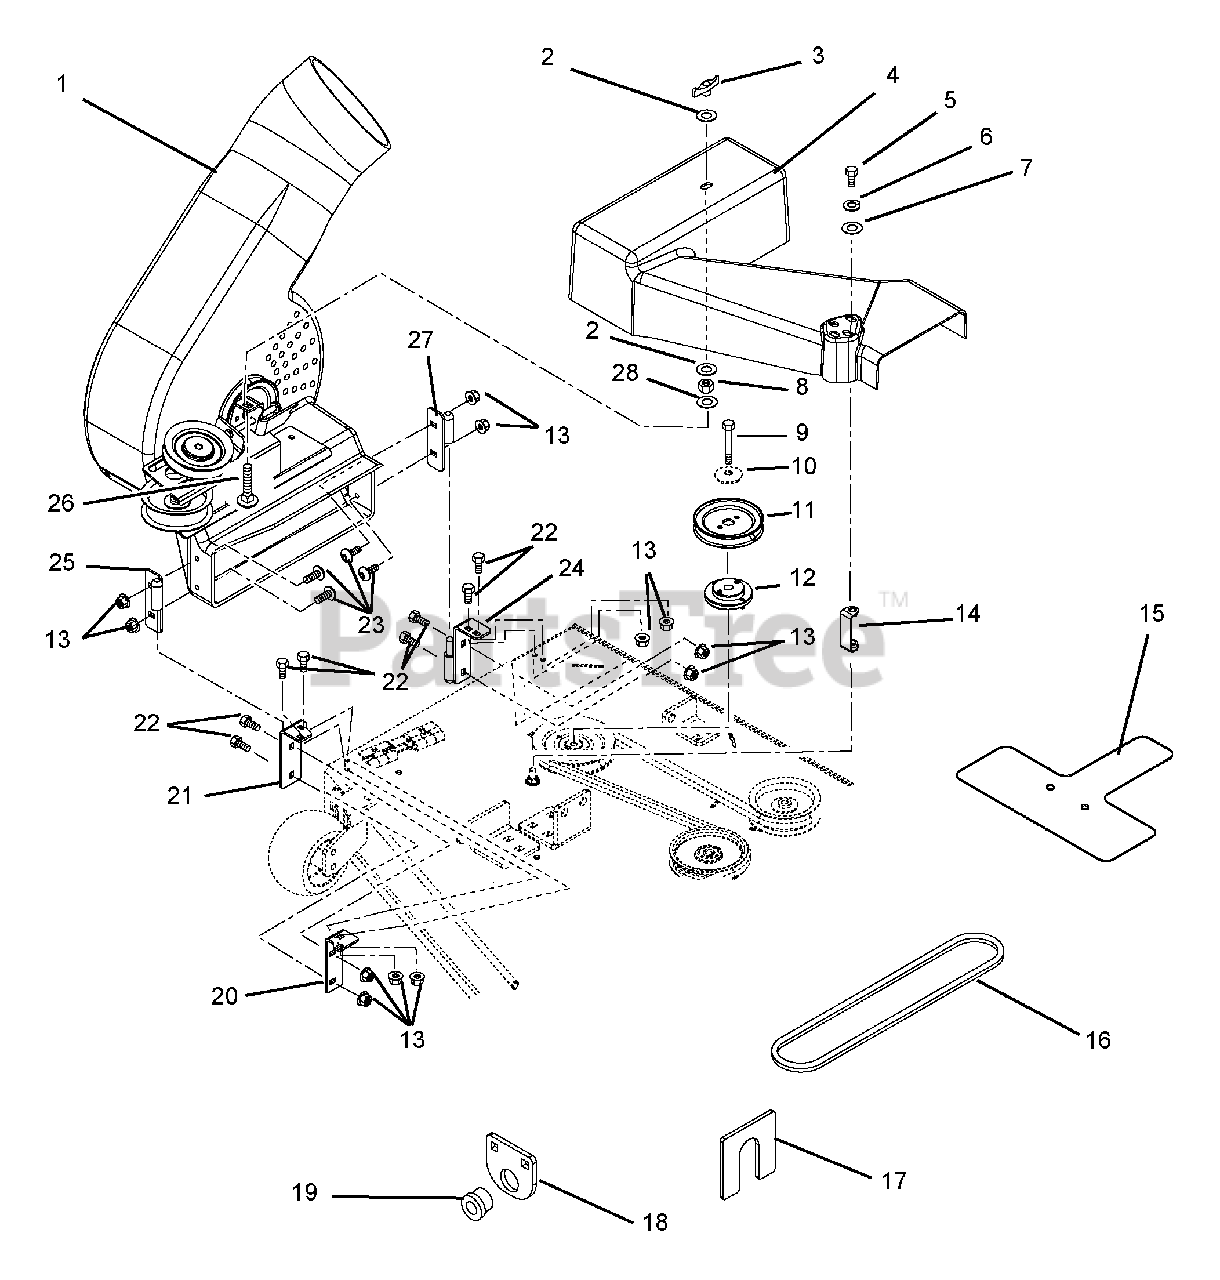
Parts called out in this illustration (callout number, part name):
1	Housing, Blower
2	Washer-Flat-Steel.38 x 1.50 x .062
3	Knob- Wing .312-18
4	Belt Cover
5	Bolt-Hex .38-16 x .75 - Grade 5
6	Washer-Locking .38 x .094 Regular
7	Washer-Flat-Steel .438 x 1.00 x .083
8	Nut-Jam .312-18
9	Bolt-Hex .38-16 x 1.75 - Grade 8
10	Washer, Cupped, .375
11	Sheave, 3.00 Diameter
11	Sheave, 4.00 Diameter
12	Assembly, Sheave Adapter
13	Nut-Locking-Top-Flange .25-20
14	Spacer, Cover
15	Guard, Finger
16	V-Belt
17	Lift Plate
18	Bracket,Rear Pivot
19	Bushing-Flange 1.000 x 1.12 x .62 x 1.50
20	Bracket, Front
21	Weldment, Front Mount Bracket
22	Bolt-Hex .25-20 x .75- Grade 5
23	Screw-Machine .25-20 x .75
24	Weldment, Rear Mount Bracket
25	Weldment, Housing Mount Right Hand
26	Bolt-Round Head Square Neck .31-18 x 1.50
27	Weldment, Housing Mount Left Hand
28	Washer-Flat-Steel .312 x .734 x .065
